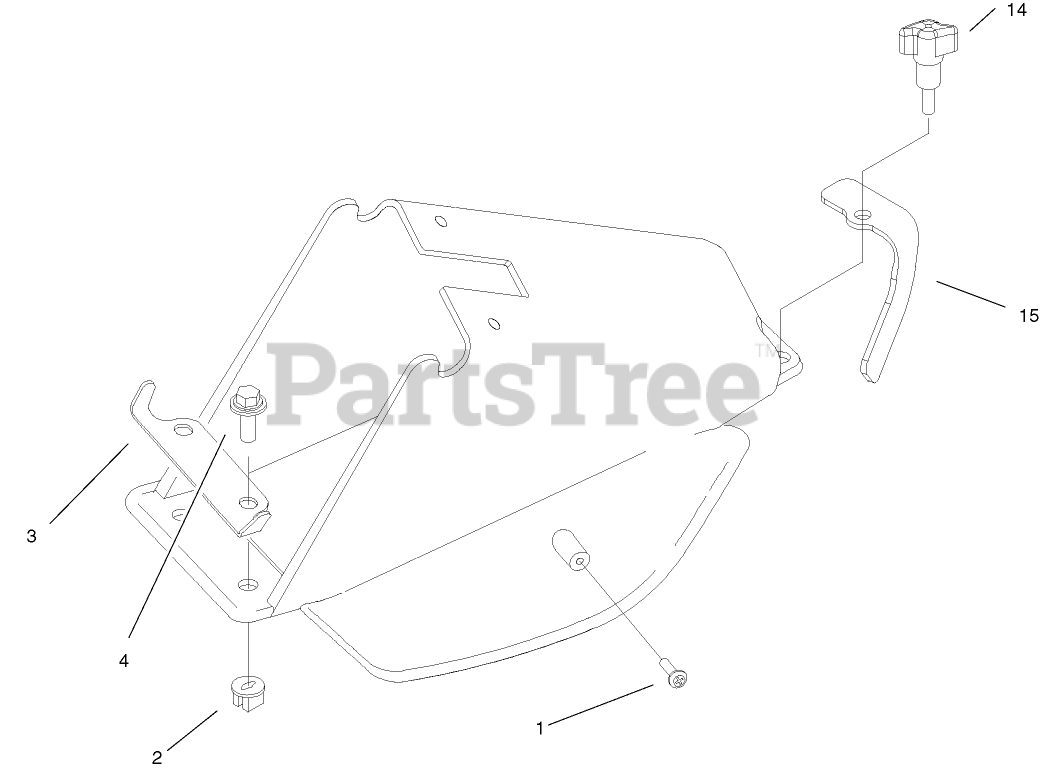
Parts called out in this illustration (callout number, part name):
1	SCREW-PPH
4	SCREW-HWH
15	CLAMP-DOOR
